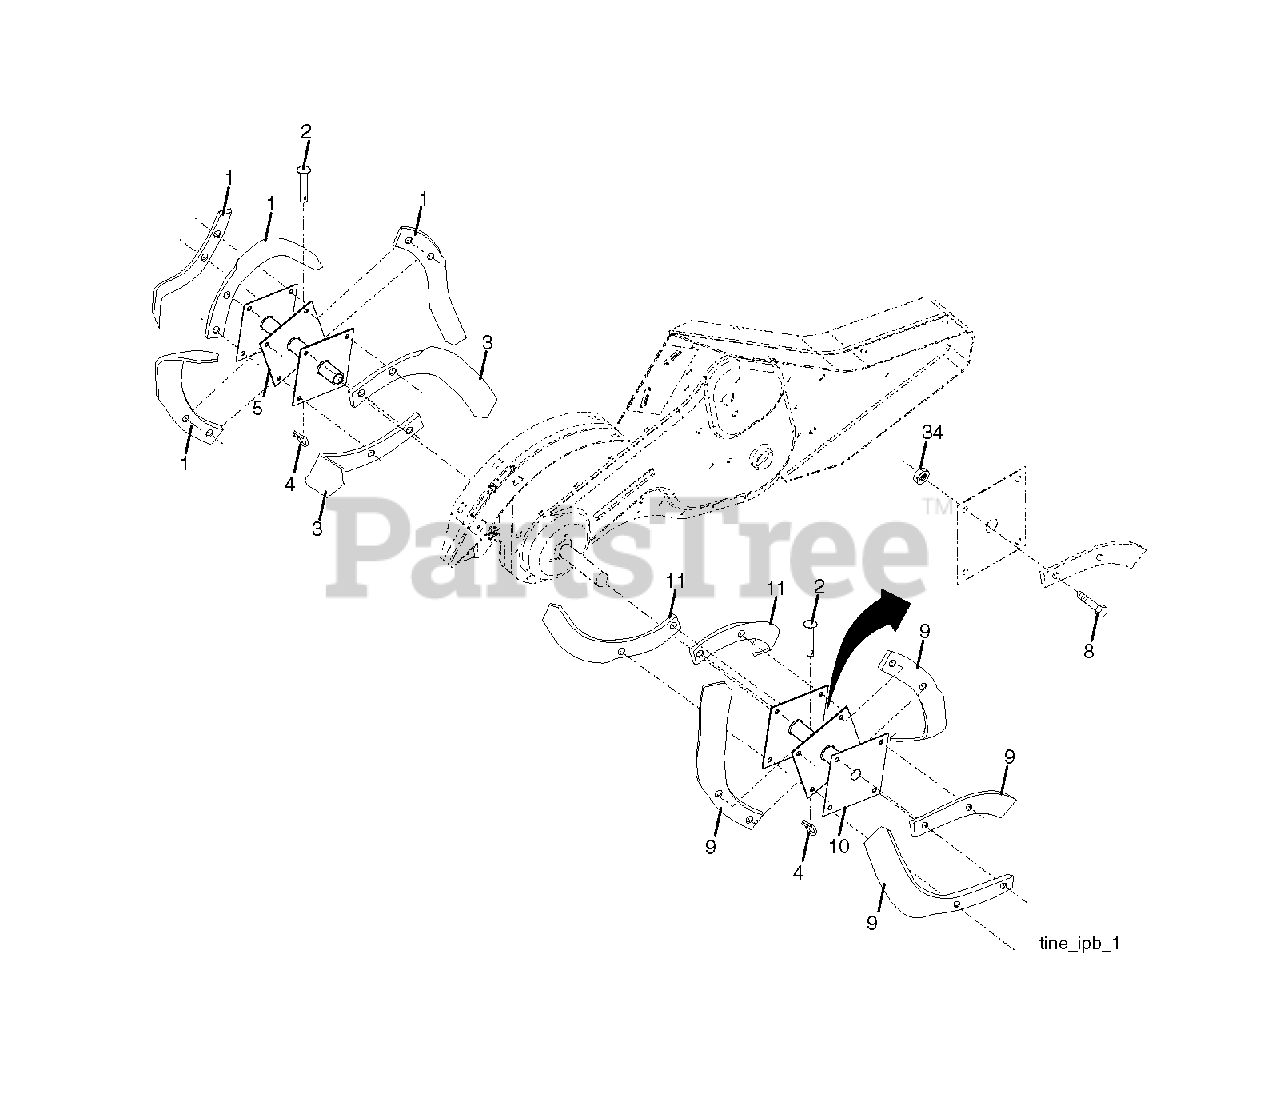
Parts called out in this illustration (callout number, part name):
1	TINE TI
4	SPRING RETAINER
5	HUB & PLATE ASM LH
8	BOLT.HEX.001X20.37-24X1.ZINC
9	TINE TI
10	HUB & PLATE ASM RH
11	TINE.RH.12"(72R)
34	NUT CROWNLOCK 3/8-24
